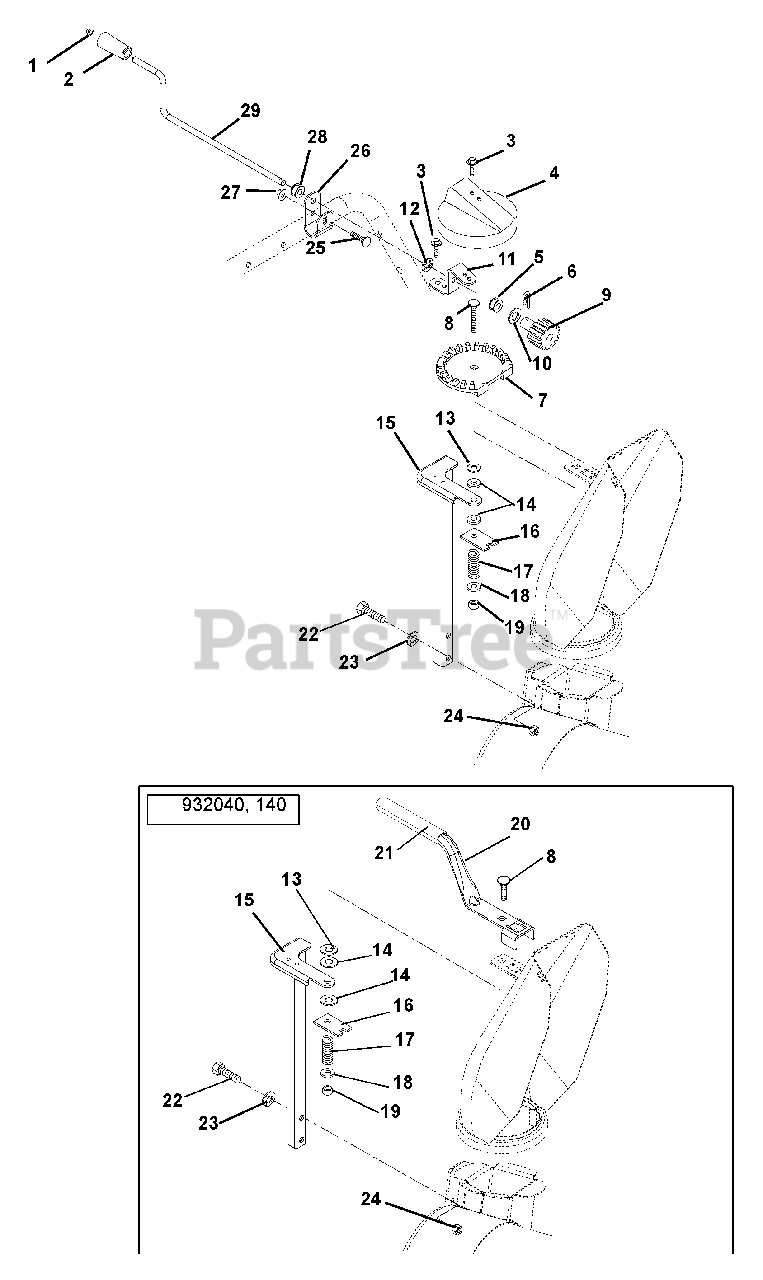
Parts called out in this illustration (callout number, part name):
1	CAP, 3/8 ROD YWZC
2	KNOB, CHUTE CRANK
3	@SCR-TAP .25-20X.50 HWH TR YWZ
4	GEAR COVER
5	BUSHING, POLYLINER-.63 SNAPIN
6	PIN, SPRING CLIP
7	CHUTE GEAR
8	@BLT-RDHDSQNK .38-16X2.50 G5YZ
9	BRACKET W/PINION GEAR
10	WSHR-THRST .625 X 1.0 X .03
11	BRACKET, PINION GEAR
12	PUSHNUT .625
13	WSHR-FL-STL .380X1.50X.062 YWZ
14	FRICTION WASHER
15	WELDMENT, PEDESTAL CHUTE MOUNT
16	PLATE, FRICTION
17	SG-COMP .187X.56X1.62
18	@WSHR-FL-STL.406X.812X.065 YWZ
19	@NUT-LK-CTR .38-16 YWZC
20	HANDLE, CHUTE ROTATION
21	GRIP, CHUTE HANDLE, ORANGE
22	@BLT-HEX .38-16X1.75 GR5 YWZC
23	@WSHR-LK .38X.094 REG YWZC
24	@NUT-LK-TOP-FLG .38-16 YWZC
25	@BLT-RDHDSQNK .31-18X1.75 G5YZ
26	BRACKET, CRANK SUPPORT
27	@NUT-LK-TOP-FLG .31-18 YWZC
28	BUSHING, POLYLINER-.38 SNAPIN
29	ROD, CHUTE CRANK
